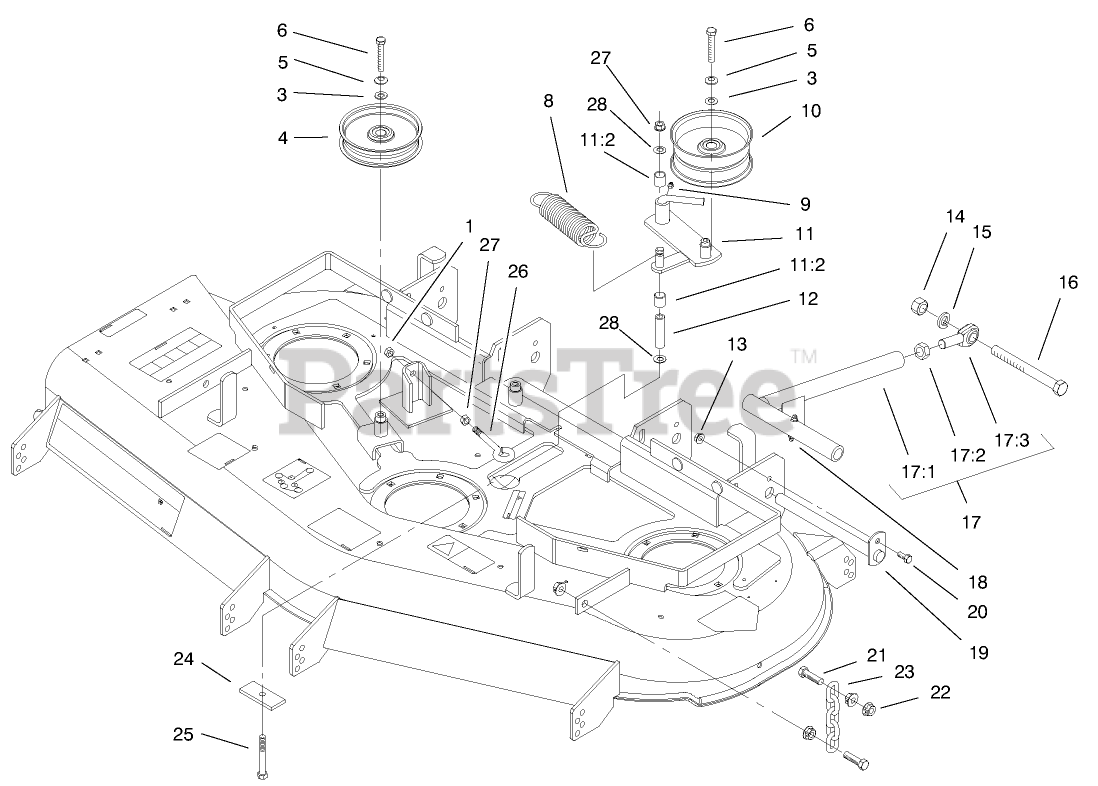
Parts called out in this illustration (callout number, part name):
1	NUT-HEX
3	WASHER-FLAT
4	Pulley-Idler
5	Washer
6	SCREW-HH
8	Spring-Extension
9	Zerk-Grease
10	Pulley
11	IDLER ARM ASM
11:2	Bearing-Pivot
12	Bushing
13	NUT-LOCK NI
14	NUT-HEX
15	WASHER-LOCK
16	Screw-HH
17	Strut ASM
17:1	Strut
17:2	NUT-HEX
17:3	Rod End
18	FITTING-STRAIGHT
19	Pin-Strut
20	SCREW-HH
21	SCREW-HH
22	NUT-HF
23	Chain-Lift
24	PLATE-RETAINER, BOLT
25	Screw-HH
26	BOLT-EYE
27	NUT-LOCK, NI
28	Washer-hardened
